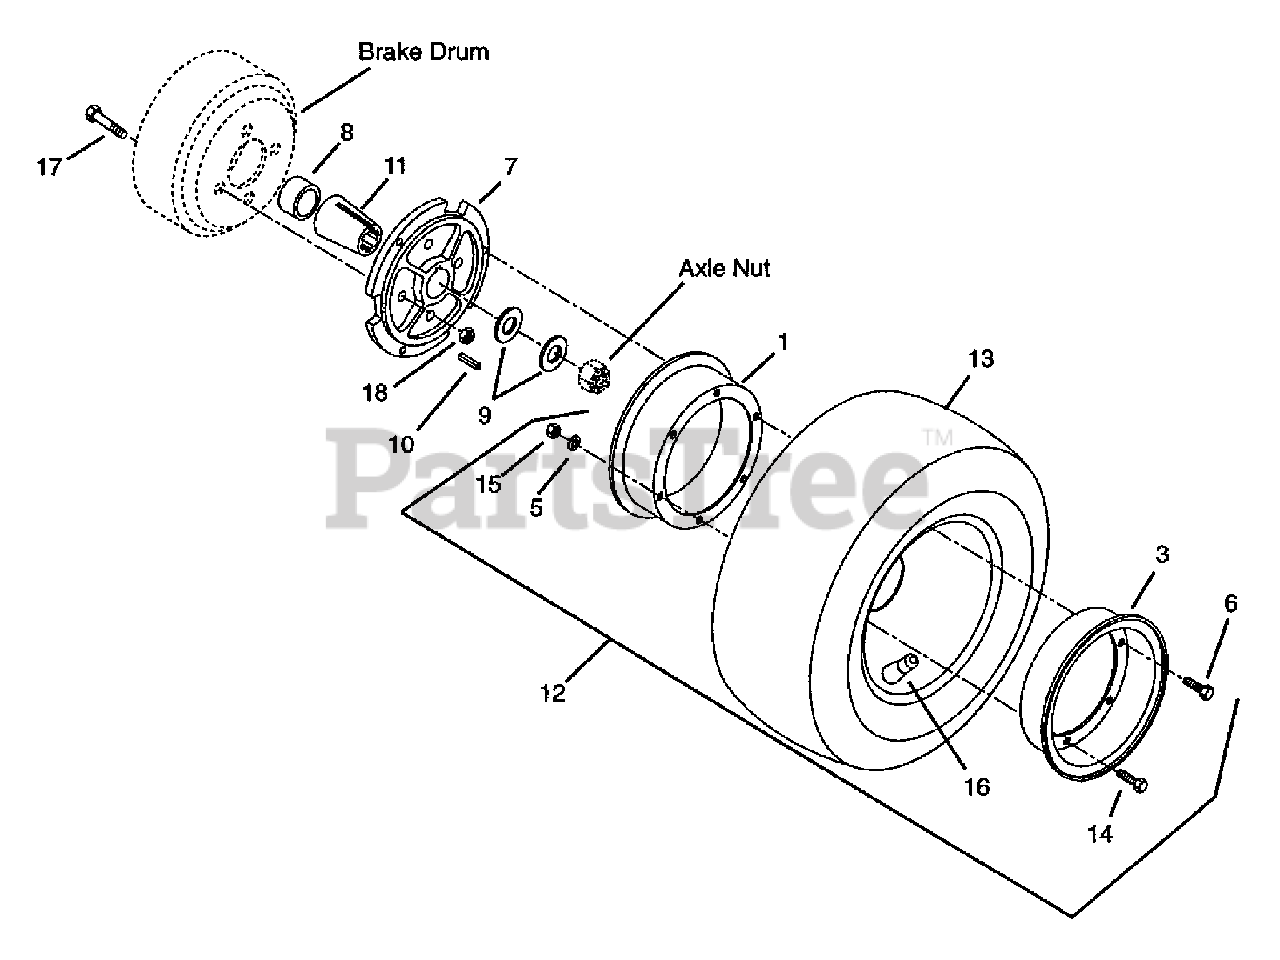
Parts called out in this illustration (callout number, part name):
1	Wheel 7.71 x 1.25 (104)
3	Wheel-Disc 6.75 x 9.219 (104)
5	Washer-Locking .375 x .094
6	Bolt-Hex .38-16 x .75 Grade 5
7	Hub-Wheel
8	Bushing-Sleeve 1.02 x 1.37 x 1.13
9	Washer-Flat-Steel .812 x 2.00 x .148
10	Key-Square .248 x 1.25 x .248
11	Insert-Hub
12	Tire/Wheel Assembly 18 x 6.50-8 (105)
13	Tire 18 x 6.50-8 (105)
14	Screw-Cap-Hex Head .38-24 x .75 Grade 5 (105)
15	Nut-Hex .375-24 Grade 2 (105)
16	Valve-Stem (105)
17	Bolt-Hex .50-13 x 1.25 (models with steering brakes only)
18	Nut-Lk-Ctr .50-13 (models with steering brakes only)
